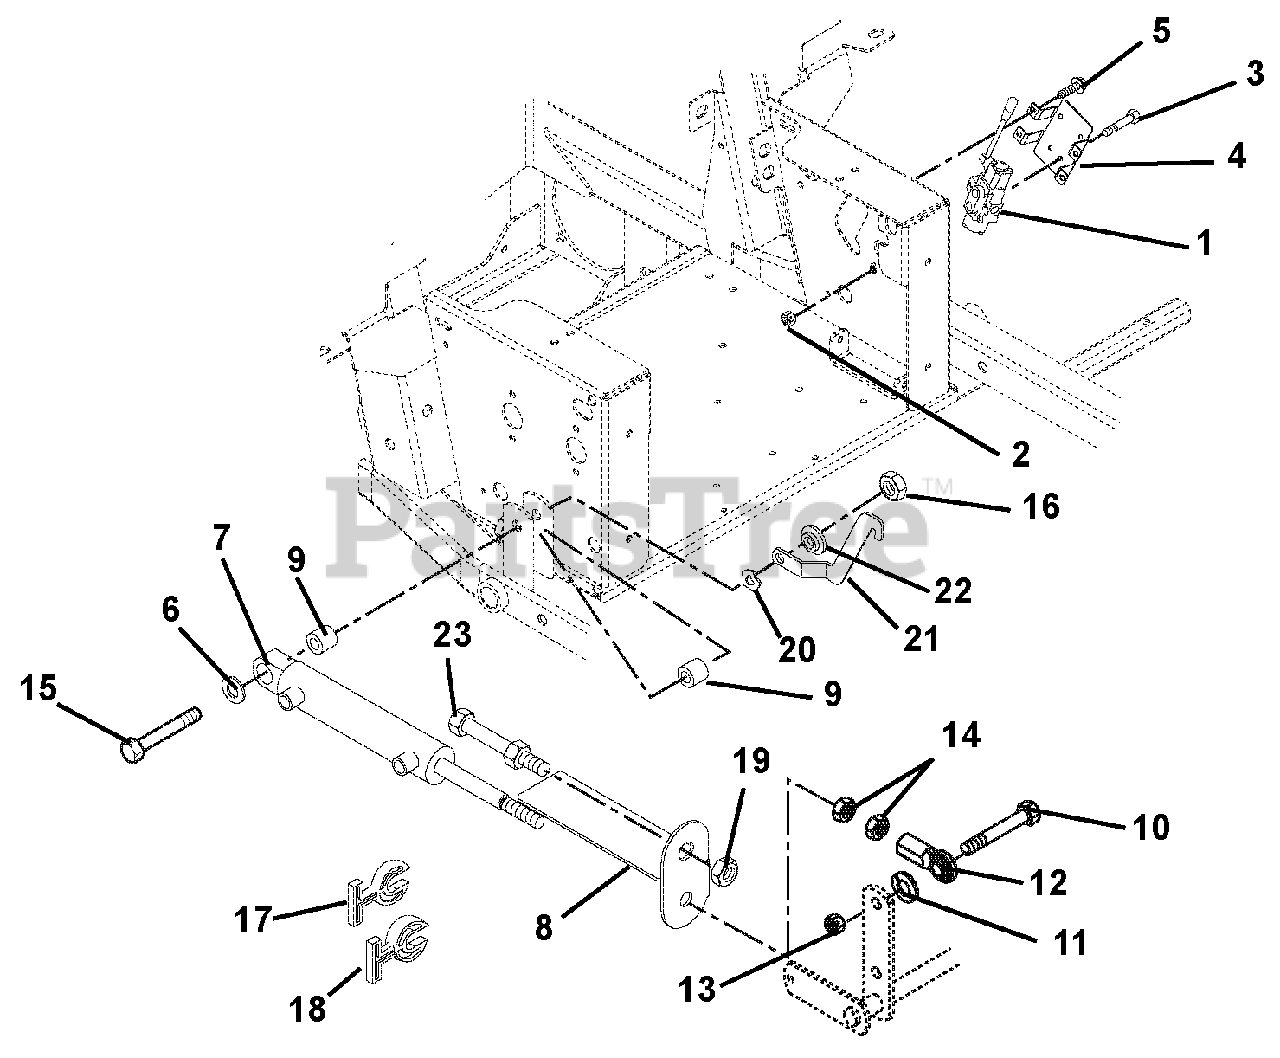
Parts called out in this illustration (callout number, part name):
1	Valve, Hydraulic
2	Nut, Locking Top Flange .31-18
3	Bolt, Hex .31-18 x 2.50 Grade 5
4	Bracket, Valve Mounting
5	Screw-Tapping .38-16 x .50 Hex Washer Head
6	Washer-Flat-Steel .515 x 1.625 x .25
7	Cylinder-Lift
8	Strap-Height of Cut Indicator
9	Bushing .516 x 1.00 x 1.05
10	Bolt-Hex .62-11 x 2.25 Grade 8
11	Washer-Lock .62 x .156
12	Rod End-Right Hand-Female .625
13	Nut-Locking-Center .62-11
14	Nut-Jam .625-18
15	Bolt-Hex .50-13 x 3.75 Grade 5
16	Nut, Locking Top Flange .50-13
17	Stop, Cylinder .34 Thick
18	Stop, Cylinder .68 Thick
19	Nut, Jam .75-16
20	Washer, Wave .076 x 1.12 x .08
21	Latch, Floor Board
22	Bushing-Flange .515 x .75 x .275 x 1.12
